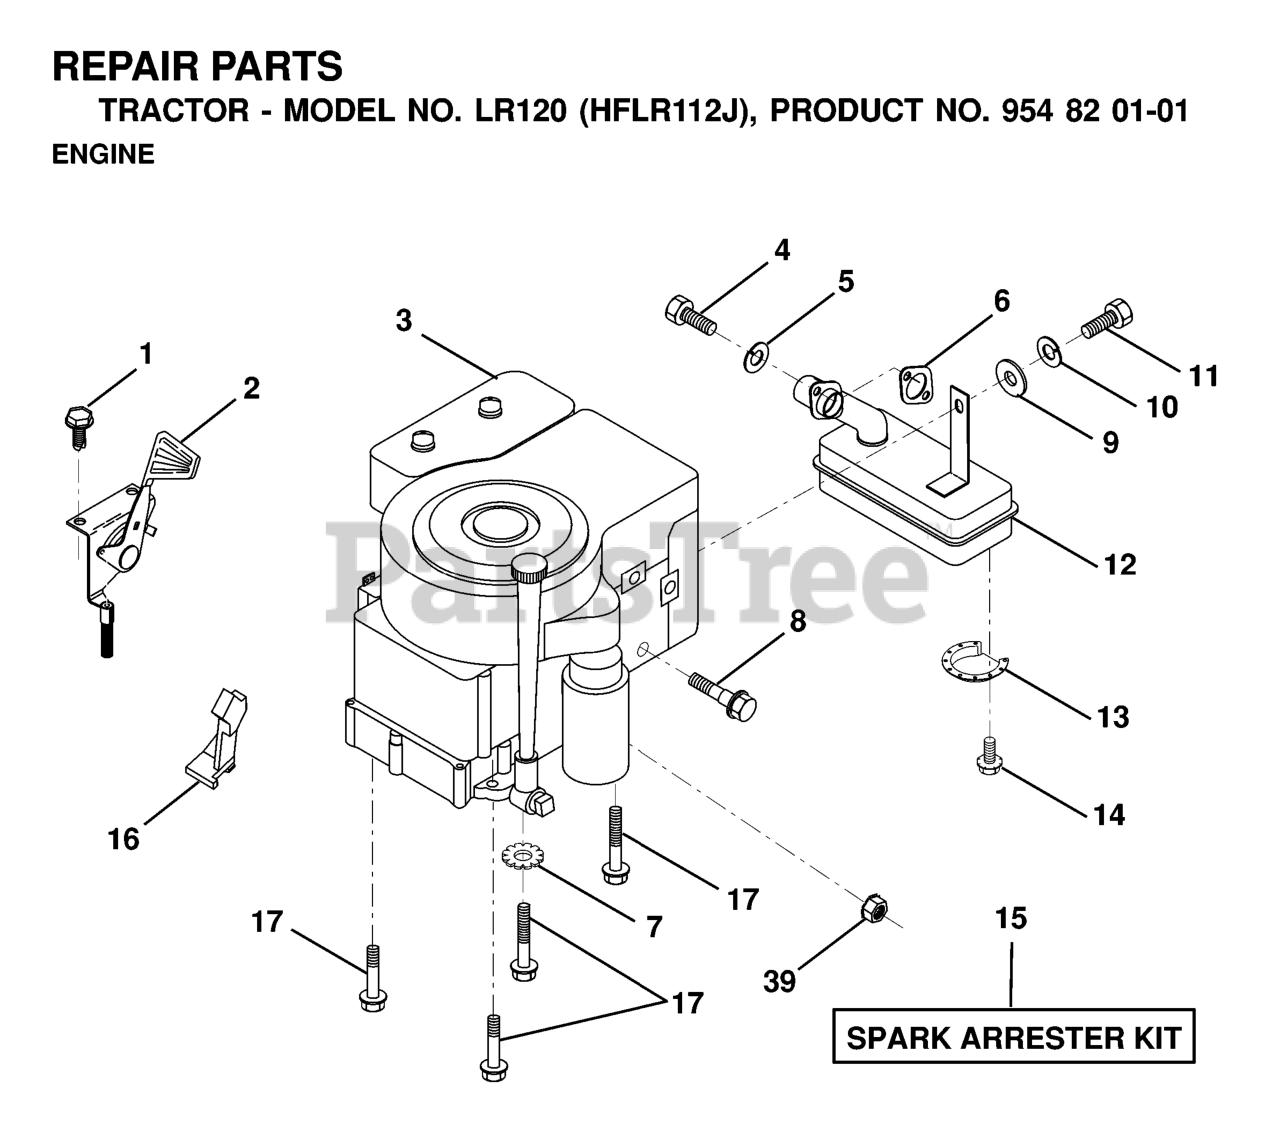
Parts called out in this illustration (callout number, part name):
1	SCREW LT
2	CONTROL.TH/CH.RH.BLK.FLG.EEC
4	SCREW
5	WASHER.LOCK.HVY.HLCL.SPR.5/16
6	REPL BY 532 27 22-93
7	LOCKWASHER
9	WASHER
10	LOCKWASHER
12	MUFFLER.SINGLE.B&S.12HP
13	DEFL MUFFLER LTV
14	SCREW
15	KIT.SPARK ARRESTOR 794945 B&S
16	STOP THROTTLE
17	SCREW LT
39	NUT FLANGE 1/4-20 STARTER NUT
